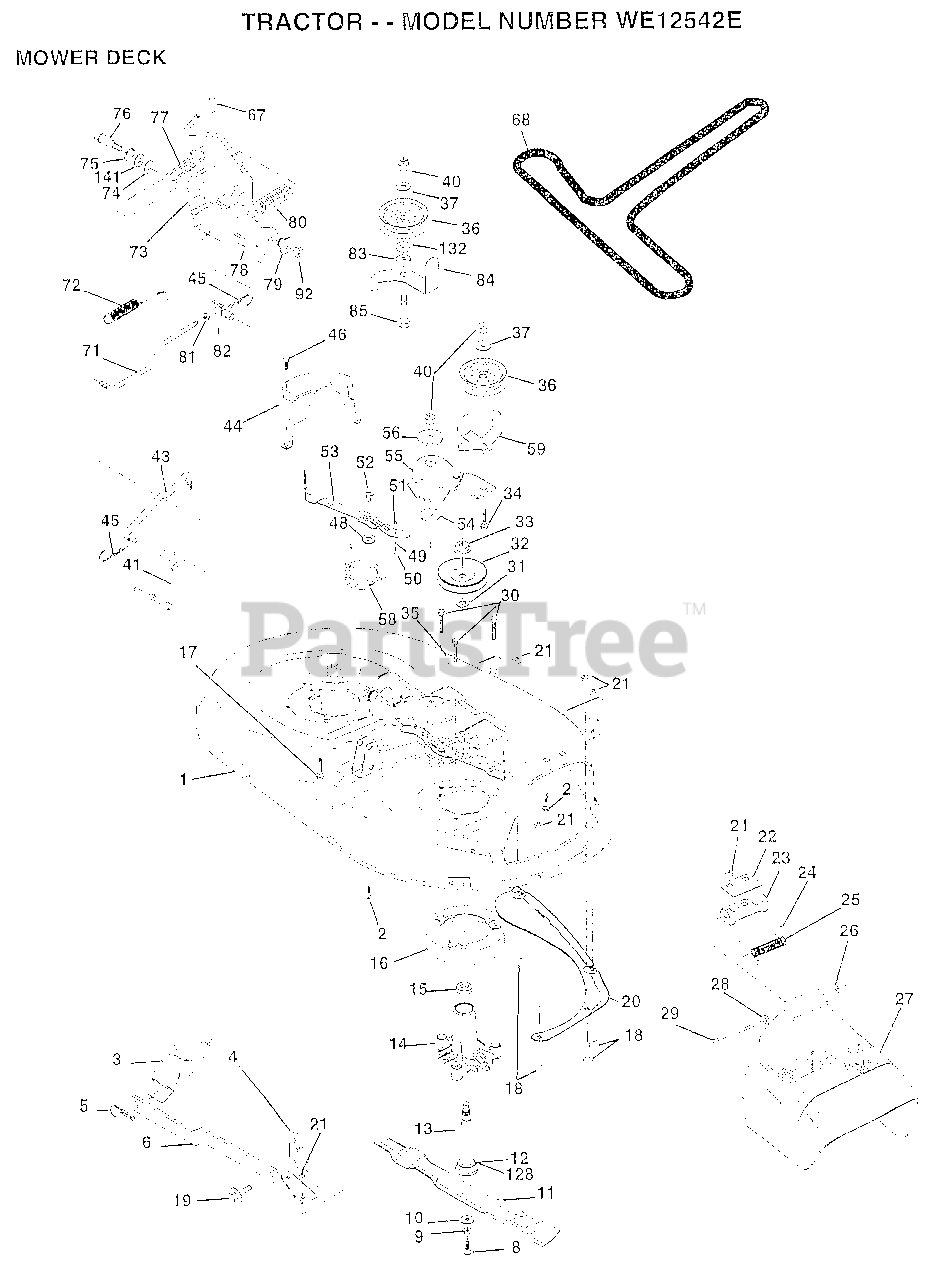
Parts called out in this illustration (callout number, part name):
1	"HOUSING ASSY.42"""
2	BOLT
3	BRKT ASM SWAY BAR
4	BRKT DECK SW BAR
8	BLADE BOLT
10	WASHER.HARD.BLADE
11	"BLADE.42"" HIPERF"
12	BEARING.BALL
14	HSG ASM MANDREL
15	BEARING
16	STRIPPER RND MWR
17	BOLT RDHD 3/8-16
18	BOLT
19	BOLT SHD 5/16-18
20	BAFFLE VORTEX 42
22	STIFFENER BRKT
23	DEFLECTOR BRKT
24	CAP-SLEEVE LT
25	SPRING TORSION
26	NUT PUSH M
27	DEFLECTOR.SHIELD
28	WASHER
29	HINGE ROD
30	"SCREW-THD ROLL,WA"
31	WASHER
32	PULLEY.MANDREL.42
34	BOLT
35	XMAS TREE FASTNER
36	FLAT IDLER PULLEY
37	WASHER
41	PIVOT ROD
43	ROD CLUTCH W/NIBS
44	GUARD MAND LH BLK
45	RETAINER M
46	SCREW.1/4-20X5/8
48	HARD SMALL WASHER
49	ROLLER ASM-CAM
50	SHOULDER BOLT
51	LOCKNUT
52	BOLT.SHLD.5/16-18
53	BRAKE PAD ARM ASM
54	HARDENED WASHER
55	ARM-IDLER
56	SPACER RETAINER
58	SPRING TORSN BRAK
59	GUARD IDLER TUV
67	KNOB.RD.7/16-14
68	BELT.V.T-PATH
71	ROD CLUTCH 38/42
72	RETURN SPRING
73	CLUTCH ARM SECOND
74	WASHER
75	RING
76	SHOULDER BOLT
77	SPRING KEEPER
78	LEVER.ASM.CLUTCH
79	BUSHING
80	SPRING.CLUTCH.MWR
81	NUT
82	TRUNION ADJ
83	WASHER
84	"KEEPER-BELT,FIXED"
85	BOLT
92	NUT
128	WASHER.FELT.
132	WASHER GT
141	WASHER .T
